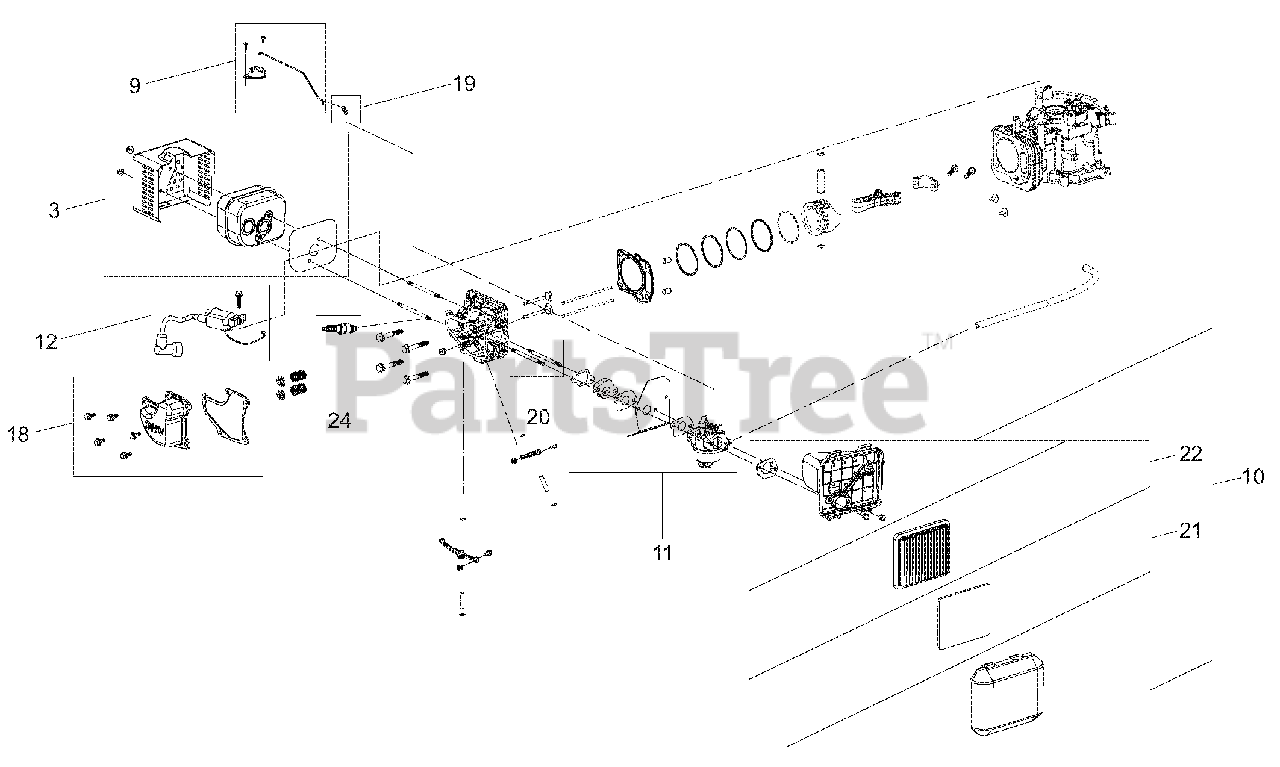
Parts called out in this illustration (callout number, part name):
1	AIR VANE CHOKE KIT
2	GOVERNOR ARM KIT
3	MUFFLER AND SHIELD KIT
4	FLYWHEEL AND FAN KIT – RECOIL START
5	KIT BRAKE ASSEMBLY – RECOIL
6	KIT BRAKE ASSEMBLY – ELECTRIC
7	KIT ARIENS STYLE
8	KIT FLYWHEEL SHIELD
9	THERMAL CHOKE CONTROL KIT
10	KIT-AIR CLEANER ASM, 2 HINGE
11	CARBURETOR COMPLETE KIT
12	IGNITION COIL KIT
13	SEAL AND GASKET KIT
14	FLYWHEEL AND FAN KIT – ELECTRIC START
16	STARTER KIT – ELECTRIC START
17	WIRE HARNESS KIT
18	KIT-VALVE COVER (1P65FA)
19	LOCK-THROTTLE
20	STUD-INTAKE
21	AIR FILTER, FOAM PRE-FILTER
22	AIR FILTER ELEMENT
23	FUEL LINE WITH STRAINER
24	SPARK PLUG
25	OIL FILTER TUBE/CAP
26	GAS CAP WITH CANISTER
27	FUEL TANK
28	RECOIL ASSEMBLY
29	ENGINE, SERVICE, AC SERIES
29	ENGINE, SERVICE, AC SERIES, ELEC
30	GOVERNOR ARM KIT – BBC
30	KILL SWITCH, ENGINE – BBC
31	FLYWHEEL AND FAN KIT – BBC
